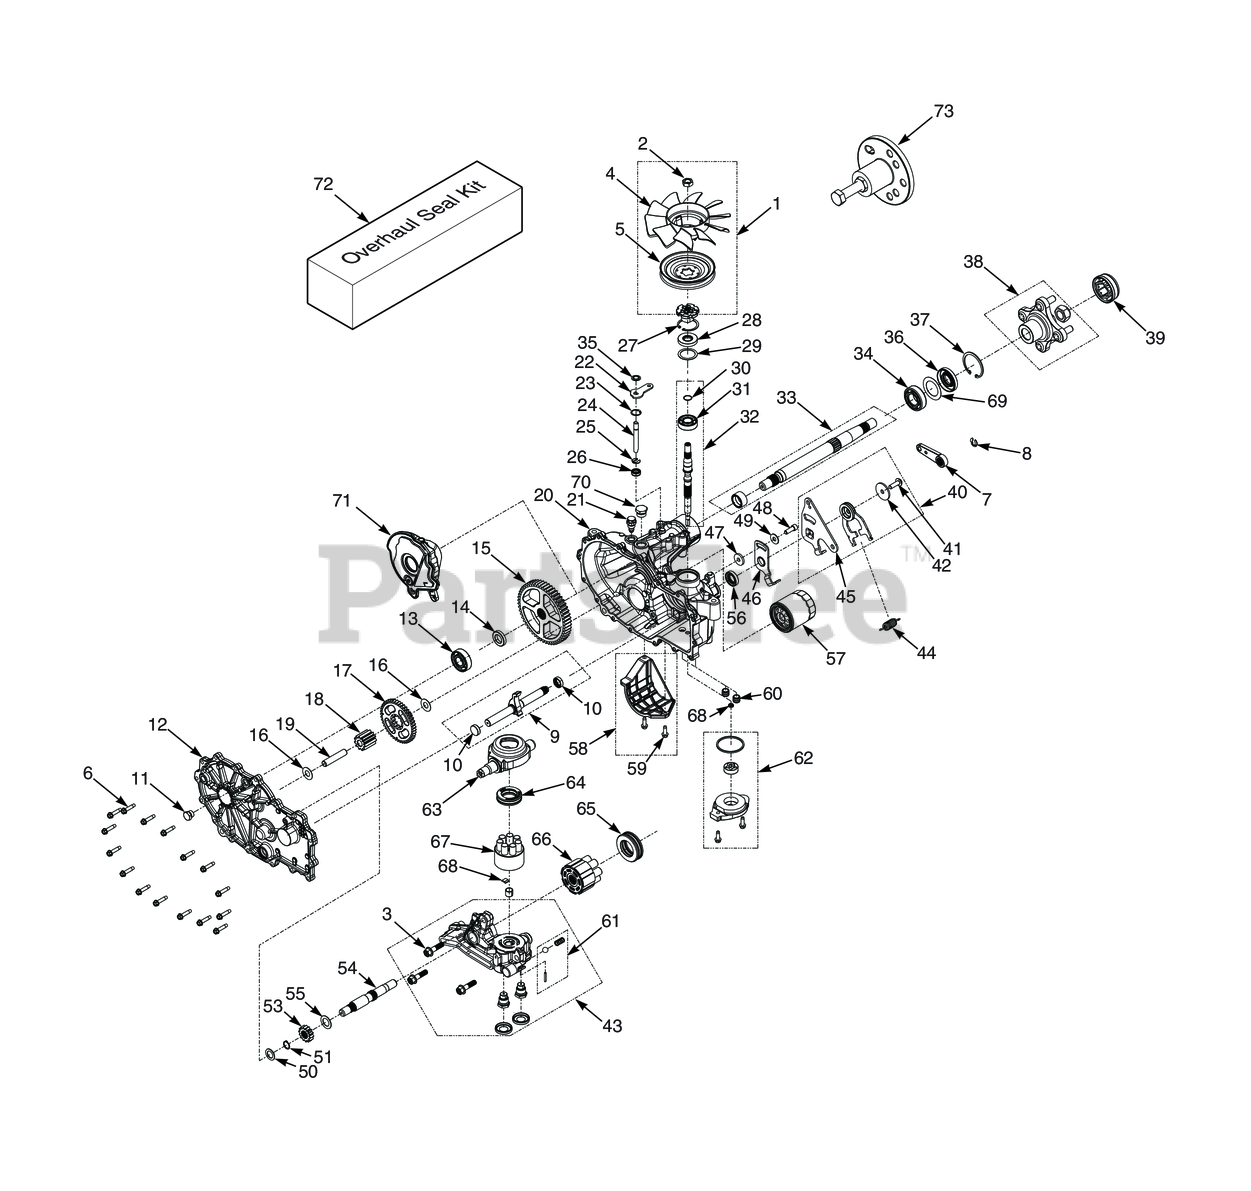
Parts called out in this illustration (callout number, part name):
1	Kit, Fan & Pulley
2	Nut, Hex Locking 1/2-20
3	Screw, Hex Flange Head 3/8-16 x 1-1/2"
4	Fan (order through Hydro-Gear)
5	Pulley, Cupped 4-1/2" Dia.
5	Hub, Pulley
6	Bolt, Hex Head 1/4-20 x 1-1/8"
7	Handle, Brake
8	Ring, Retaining External .375"
9	Kit, Outboard, RH Rot B / LH Rot A (LH)
9	Kit, Outboard, RH Rot A / LH Rot B (RH)
10	O-Ring, -111 x .103 x 424
11	Plug, External Hex Vent 9/16-18
12	Kit, Side Cover RH
12	Kit, Side Cover LH
13	Kit, Bearing
14	Spacer, .750 x 1.320 x .257
15	Gear, 54T
16	Washer, .5 x 1.0 x .03
17	Gear, 45T
18	Gear, 11T Steel
19	Jackshaft Pin
20	Kit, Main Housing RH Charge, Control
20	Kit, Main Housing LH, Charge, Control
22	Arm, By-Pass
23	R i n g , Retaining .750 Internal
24	Rod, By-Pass
25	Ring, .Retaining .375 External
26	Seal, Lip, .375 x .75 x .25
27	R i n g , Retaining 2.06 Internal
28	Seal, Lip 17 x 40 x 7
29	Washer, 1.23 x 1.56 x .04
30	Ring, Retaining Wire
31	Bearing, Ball 17 x 40 x 12 Open
32	Kit, Input Shaft
33	Kit, Shaft, Axle
34	Bearing, Ball 1.0 x 52 x 15 Open
35	Ring, Retainging .375 External
36	Seal, Lip TC4 1.0 x 2.06 x .38
37	R i n g , Retaining 2.06 Internal
38	Hub, 4-Bolt
39	Cap, Axle
40	Kit, RTN Bi-Directional (Left Side)
41	Bolt, Hex Head Cap Screw 5/16-24 x 1" Patch
42	Washer, .343 x 1.5 x .062
43	Kit, Center Section RH
43	Kit, Center Section LH
44	Spring, Extension, RTN - 44lbs
45	Arm, Control
46	Arm, Neutral (Right Side)
46	Arm, Neutral (Left Side)
47	Spacer, .32 ID x 1.005 OD x .1495 Thk
48	Bolt, Hex Head Cap Screw 5/16-24 x 1" Patch
49	Washer, 7/16 x 7/8 OD x .06 HT
50	Washer, HT .62 ID x 1.0 OD x .05 Thick
51	Ring, Retaining .625
52	Pawl, Brake
53	Gear, 14T Steel
54	Shaft, Motor
55	Washer, .72 x 1.16 x .04
56	Seal, Lip 18 x 32 x 7
57	Filter, Oil
58	Kit, Filter Guard (LH)
59	Bolt, 1/4-20 x 3/4"
60	Tube, Charge Triple O-ring
61	Kit, Charge Relief
62	Kit, Charge Pump
63	Trunnion, Swashplate
64	Ball Thrust Bearing
65	Thrust Ball Bearing Assembly
66	Kit, 16cc Cylinder Block Assembly (steam
67	Kit, Cylinder Block
68	Kit, Gerotor Seal
69	Kit, Charge Relief
70	Plug, 3/4-16
71	Expansion Tank, Internal LH
71	Expansion Tank, Internal RH
72	Kit, Seal (ZT-2800)
73	Kit, Hub Puller
